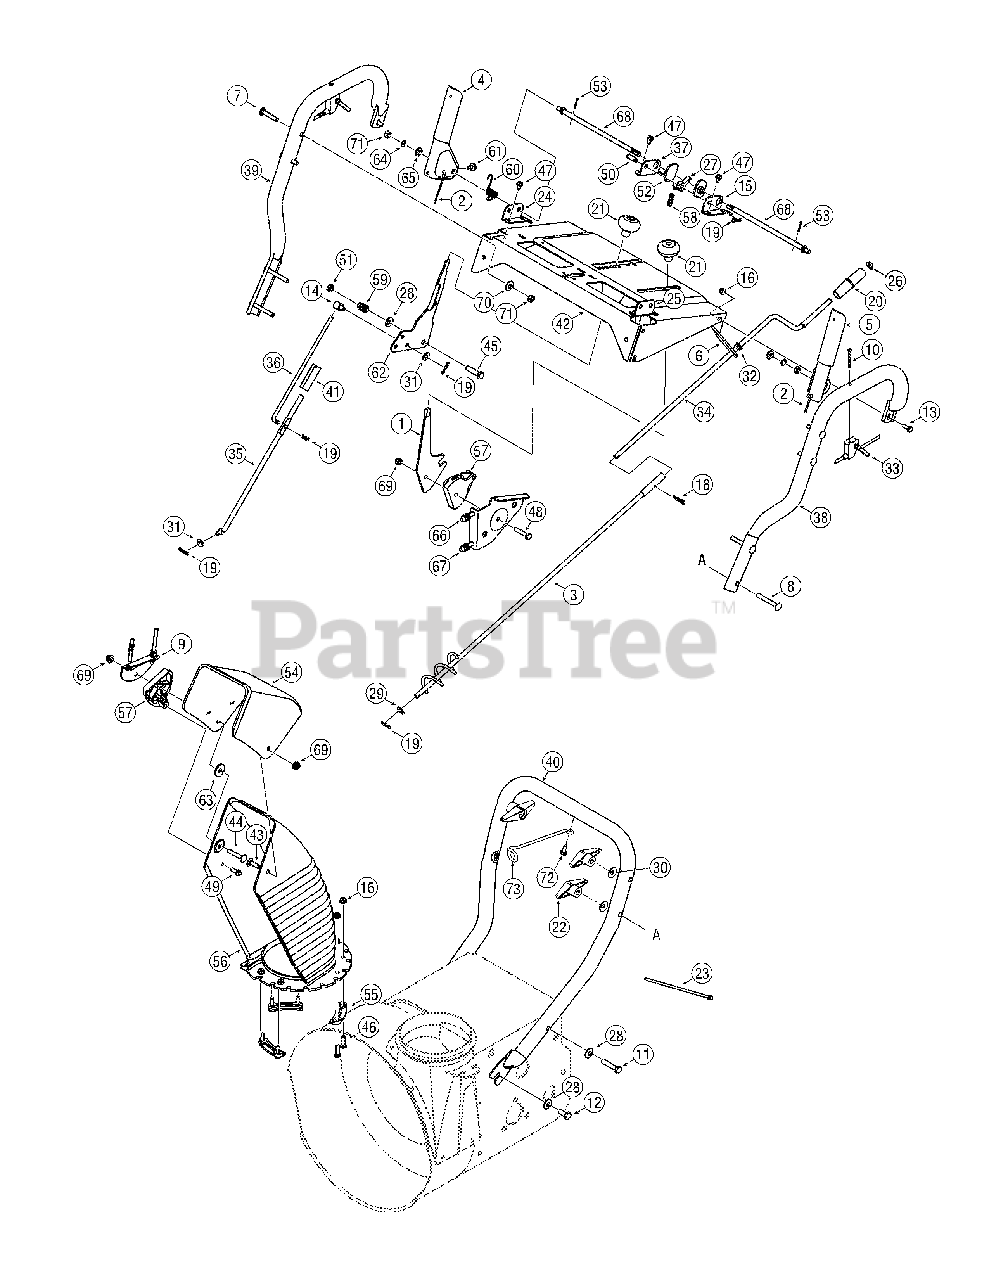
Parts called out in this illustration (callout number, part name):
2	Cable Ass’y (Auger/Drive)
5	Engagement Handle LH Black
7	Carriage Bolt 5/16-18 x 1.75" Lg.
8	Carriage Bolt 5/16-18 X 2.50
10	Screw, #10-24 x 1.75
11	Hex Screw 3/8-16 x 2.0 Gr. 5
12	Hex TT Screw 3/8-16 x .75
13	Hex Cap Bolt 1/4-20 x .75" Lg.
14	Ad just ment Ferrule
16	Hex L-Flanged Nut 1/4-20 Gr. F Nylon
18	Internal Cotter Pin
19	Int. Cotter Pin .072 x 1.13" Lg.
20	Knob 1.0 x 3.2
26	Push Nut 3/8" Rod
27	Cam Lock Pawl
28	Cupped Washer .375 ID x .870 OD x .063
29	Flat Washer .406" I.D. x .75" O.D.
30	Cupped Washer .345 ID x .88 OD x .06
31	Flat Washer .34 ID x .688 OD x .065
32	Plastic Bushing .380 ID
33	Steering Trigger
35	Lower Shift Rod
36	Upper Shift Rod
41	Connector - Shift Rod
43	Carriage Bolt 5/16-18 x 1.00" Lg
44	Carriage Bolt 5/16-18 x 1.75" Lg.
45	Hex Scr 3/8-24 x 1.50
46	Screw 1/4-20 x 1.0
47	Hex Wash S-Tapp Scr 1/4-20 x .50
48	Hex Bolt 5/16-18 x 1,50" Lg. Gr. 5
49	Hex Tapp Scr 1/4 x .75" Lg.
50	Clevis Pin .31 Dia. x 1.0" Lg.
51	Hex Nut 3/8-24
52	Cam Handle Lock
53	Cotter Pin 3/32 x .75
55	Chute Flange Keeper
58	Compression Spring .62 OD x 6.12" Lg.
59	Compression Spring .38 ID x .88 Lg
60	Tor sion Spring
61	Rub ber Bumper
63	Flat Washer .344 ID x 1.125 OD x .125
64	L-Wash 5/16 ID
65	Flat Washer (special) .350 sq. x .72 x .134
66	Chute Control Cable 66"
67	Chute Control Cable w/clip
69	Hex L-Flanged Nut 5/16-18 Gr. F Nylon
70	Flat Washer .349 ID x .879 OD x .063
71	Hex Patch L-Nut 5/16-18
72	Hex TT Screw 5/16-18 x .75
